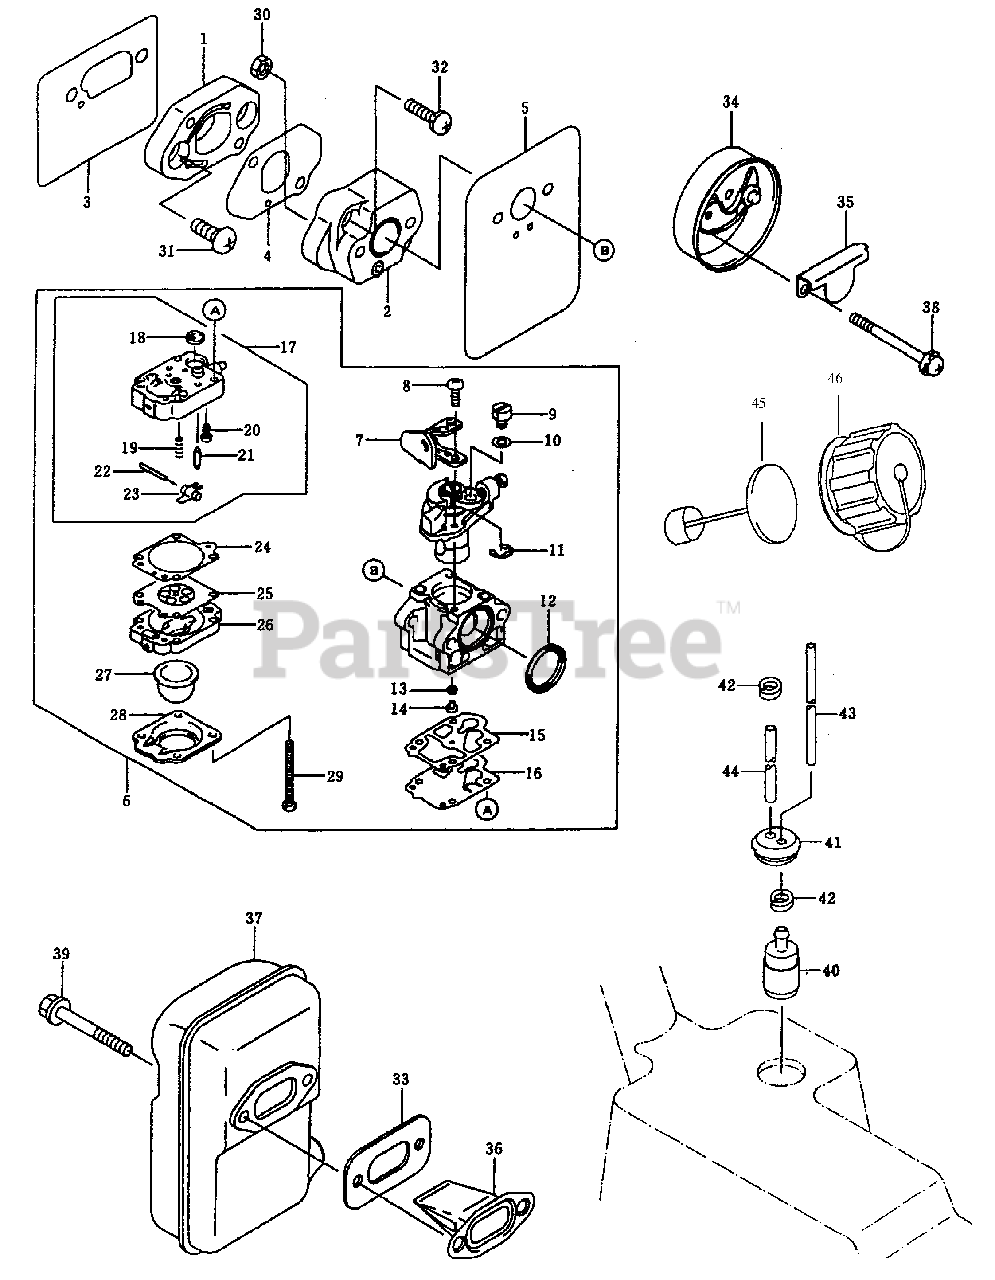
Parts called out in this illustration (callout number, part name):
2	Insulator
6	Carburetor Assembly (Inc. Ref. # 7-29)
7	Bracket
8	Screw
9	Arm
10	Washer
11	Snap Ring
12	Packing
13	O-Ring
14	Main Jet
15	Gasket
16	Diaphragm
17	Body Assembly (Incl. Ref. # 18-23)
18	Filter
19	Spring
20	Screw
21	Float Valve
22	Pin
23	Lever
24	Gasket
25	Diaphragm
26	Body
27	Priming Pump
28	Cover-Primer Pump
29	Screw
33	Muffler Gasket
34	Air Filter Case Assembly
36	Spark Arrester
37	Muffler Complete
40	Fuel Filter
41	Fuel Tank Grommet
42	Fuel Filter Clamp
45	Breather
46	Cap Assembly
